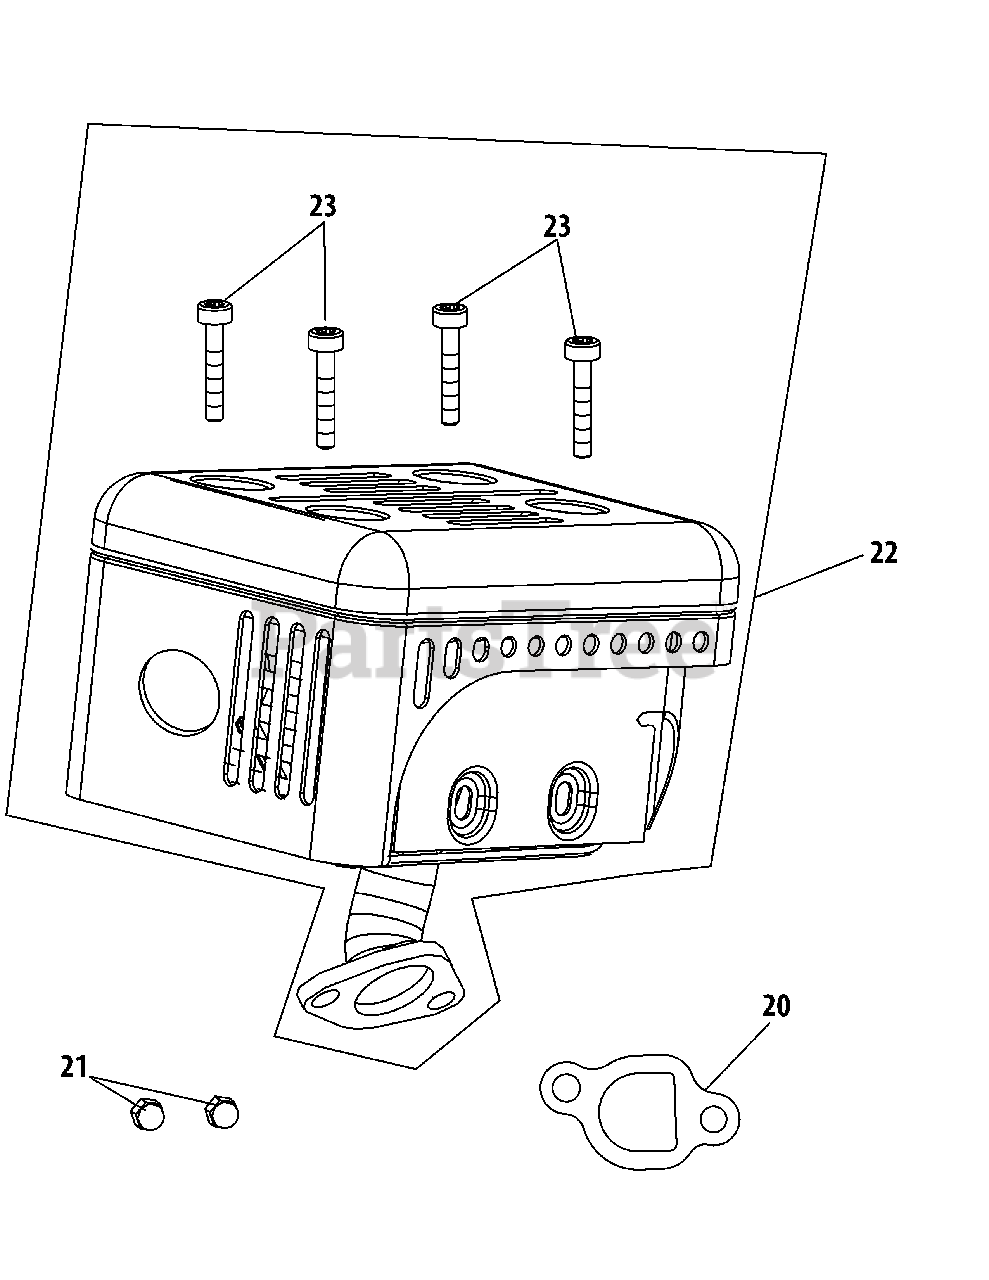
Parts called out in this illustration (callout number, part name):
20	Exhaust Pipe Gasket
21	Nut, M8
22	Muffler Assembly
23	Bolt M5×10
